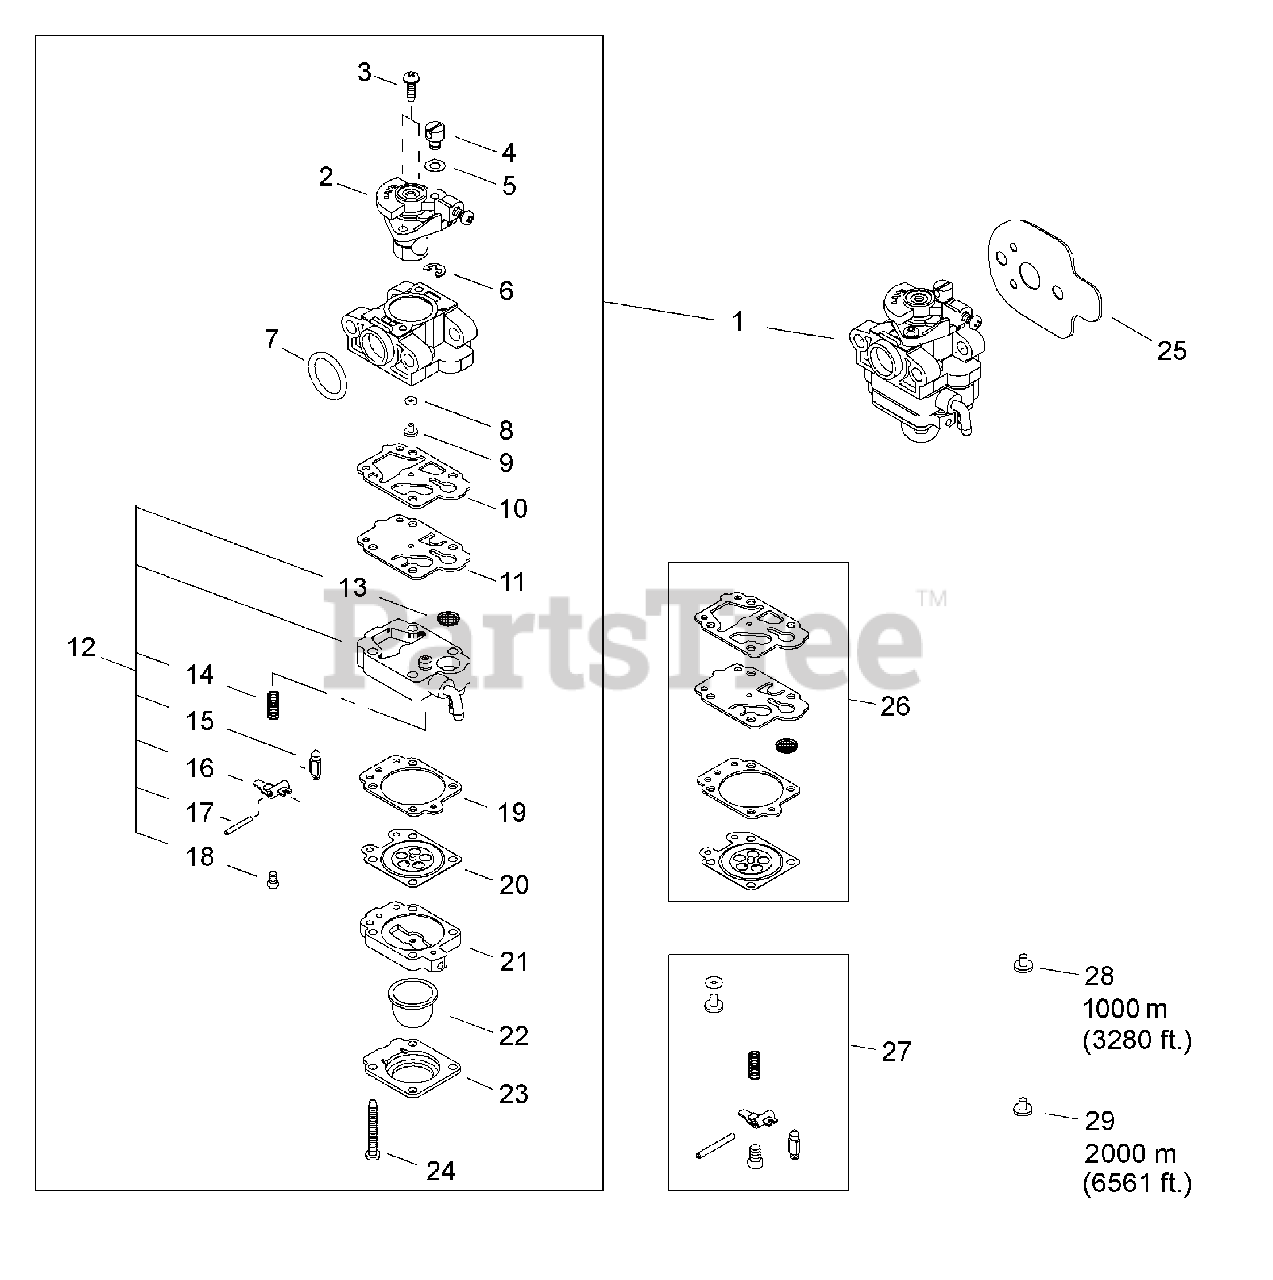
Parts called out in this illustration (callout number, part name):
1	CARBURETOR
2	VALVE ASSY, THROTTLE
3	SCREW, THROTTLE COLLAR
4	SWIVEL
5	WASHER
6	E-RING
7	O-RING 15
8	O-RING
9	JET, MAIN
10	GASKET, PUMP
11	DIAPHRAGM, PUMP
12	BODY ASSY, PUMP
13	SCREEN, FUEL INLET
14	SPRING, METERING LEVER
15	VALVE, INLET NEEDLE
16	LEVER, METERING
17	PIN, METERING LEVER
18	SCREW
19	GASKET, METERING DIAPHRAGM
20	DIAPHRAGM, METERING
21	BODY ASSY, PURGE
22	BULB, PURGE
23	RETAINER, PURGE BULB
24	SCREW
25	GASKET, INTAKE
26	GASKET / DIAPHRAGM KIT
27	VALVE KIT, INLET NEEDLE
28	JET, MAIN #40
29	JET, MAIN #39
